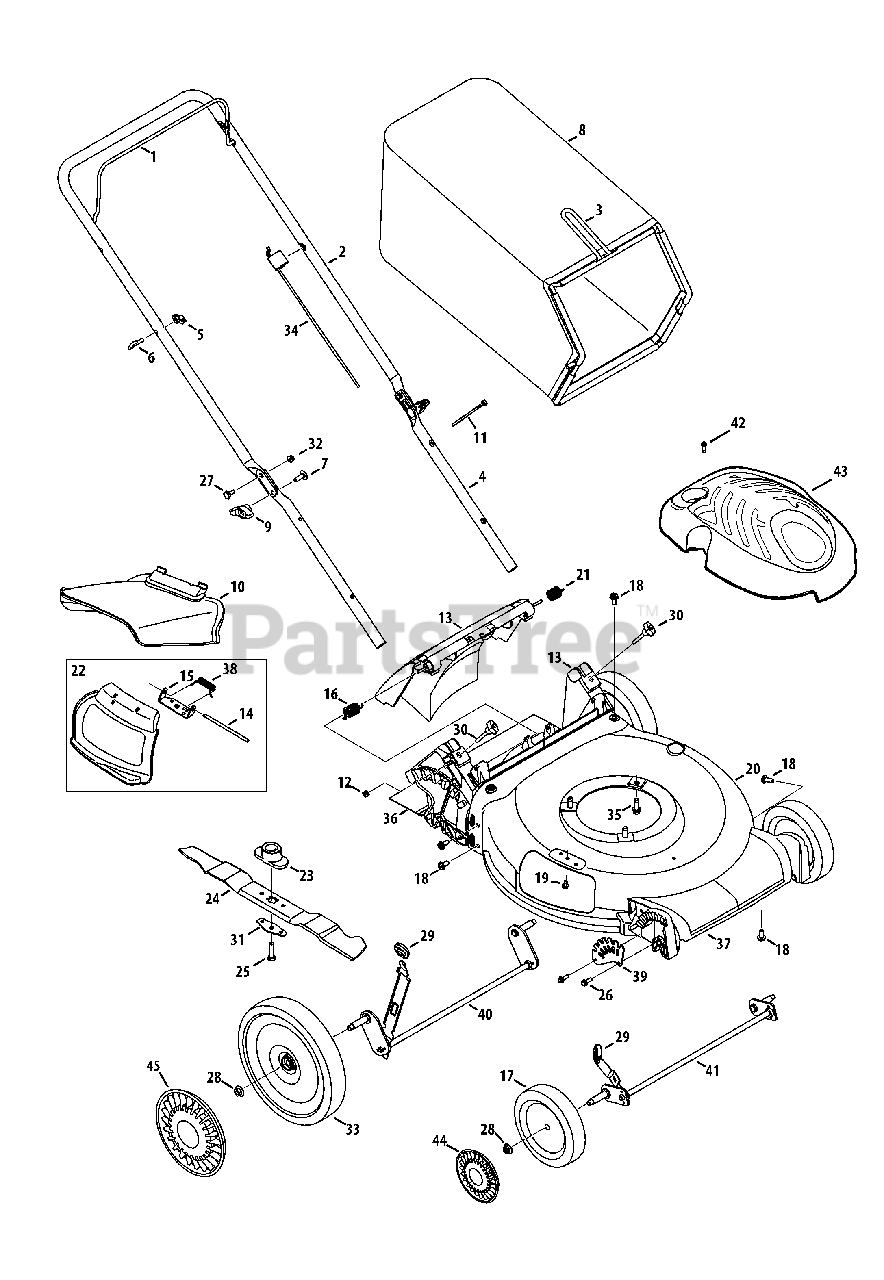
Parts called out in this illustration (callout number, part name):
1	Blade Control, Standard
2	Upper Handle, Non-Adjustable
3	Grass Catcher Frame
4	Lower Handle
5	Wing Nut
6	Rope Guide
7	Carriage Screw, 5/16-18
8	Grass Bag
9	Wing Knob, Black
10	Side Chute
11	Cable Tie
12	Nut, Sq., 1/4-20
13	Rear Discharge Door Assembly
14	Hinge Pin
15	Chute Deflector Bracket
16	Torsion Spring - RH
17	Font Wheel Gray
18	Screw, 5/16-14 x .750
19	Screw, 1/4-20 x .500
20	Deck , 21" - MTD Red
21	Torsion Spring - LH
22	Hinged Mulch Plug Assembly
23	Blade Adapter, #6 x 1.19 w/ Star
24	Mulching Blade
25	Screw , 3/8-24 x 1.50
26	Screw, 1/4-15 x .750
27	Sldr. Screw, .375 x .126 x 1/4-20
28	Flange Lock Nut, 3/8-16
29	Adjustment Lever Knob
30	Wing Nut, Black
31	Blade Bell Support
32	Nut, Flange Lock, 1/4-20
33	Rear Wheel Gray
34	Control Cable, 48"
35	TT Sems Screw, 3/8-16 x 1.0
36	Trail shield
37	Front Cover
38	Torsion Spring
39	Front Height Adjuster Plate
40	Rear Axle Assembly
41	Front Axle Assembly
42	Screw, HL, #12-16 x 1.00
43	Engine Shroud M1.1 Black
44	Hubcap, 7" w/o snaps
45	Hubcap, 11"
